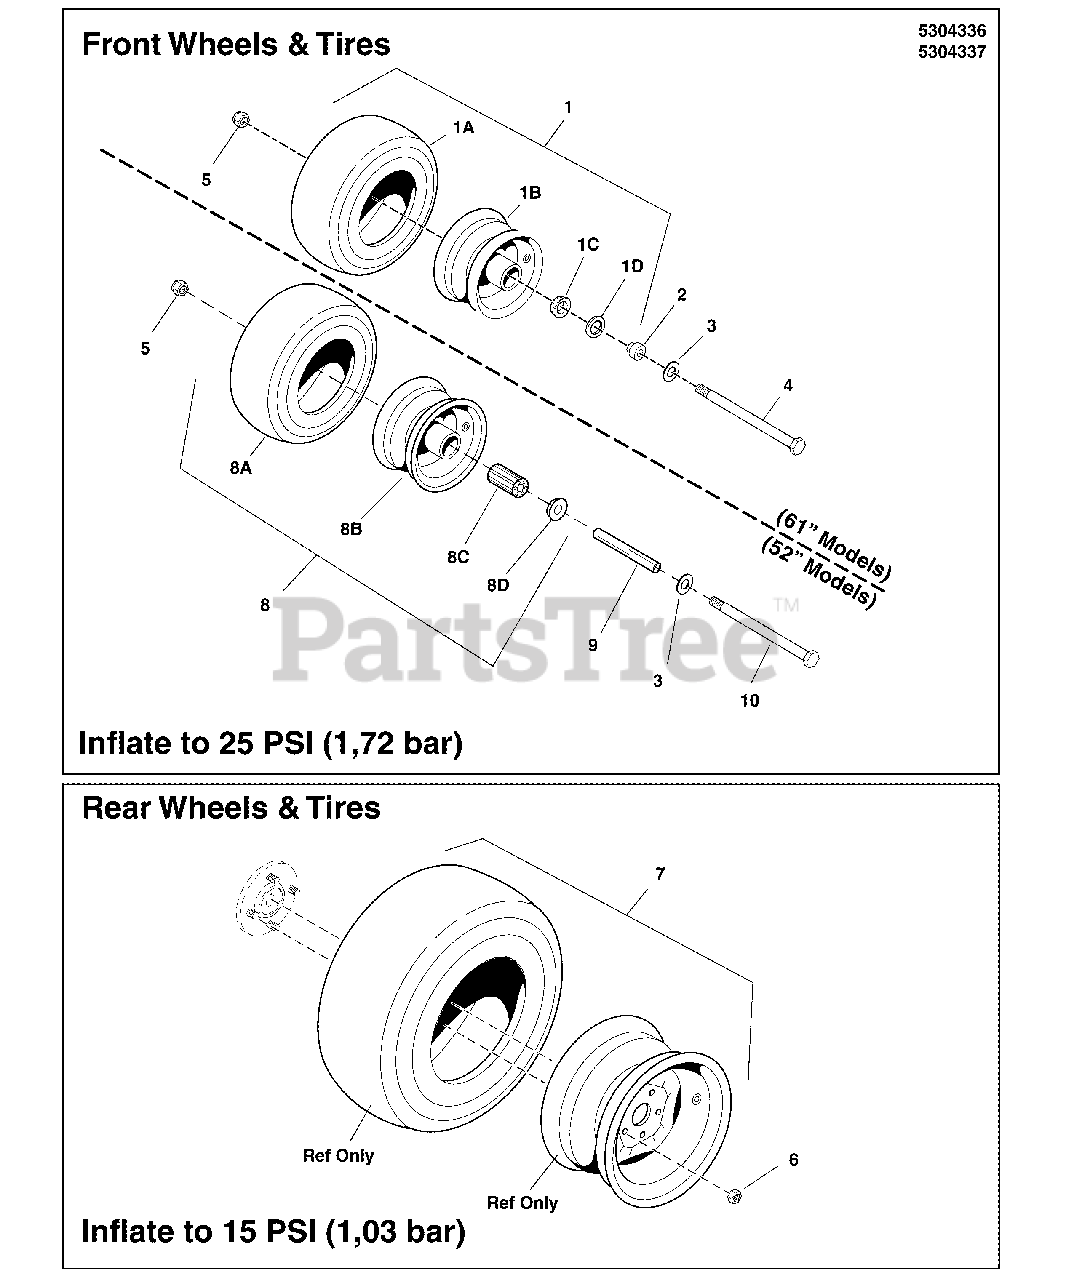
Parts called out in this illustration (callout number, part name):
1	TIRE, CASTER, 13 X 5.00-6
1A	TIRE ONLY (SV)
1B	WHEEL ASSY, 13 X 5 X 6, SILVER (SV)
1C	BEARING, TAPERED CONE
1D	SEAL, GREASE
2	ADAPTER, CASTER AXLE, CZ
3	WASHER, 1/2 SAE
4	BOLT, 1/2-13 X 8 GD5 YZ
5	NUT, 1/2-13 HEX NYLOCK FLANGE
6	NUT, 1/2-20, FOR WHEEL BOLT SILVER
7	WHEEL AND TIRE ASSY, 20X10-8 (K505)
8	WHEEL, CASTER, 11 X 4.0-5 SILVER BEAD LO
8A	TIRE, FRONT, 11 X 4.0 - 5
8B	WHEEL ASSEMBLY, 11 X 4.0 - 5 TIRE CMP
8C	BEARING, CASTER WHEEL, 11 X 4.0 - 5 BEAD LOCK
8D	BEARING, RETAINER
9	CASTER AXLE DDSH
10	BOLT, 1/2-13 X 7 GD5 CZ
